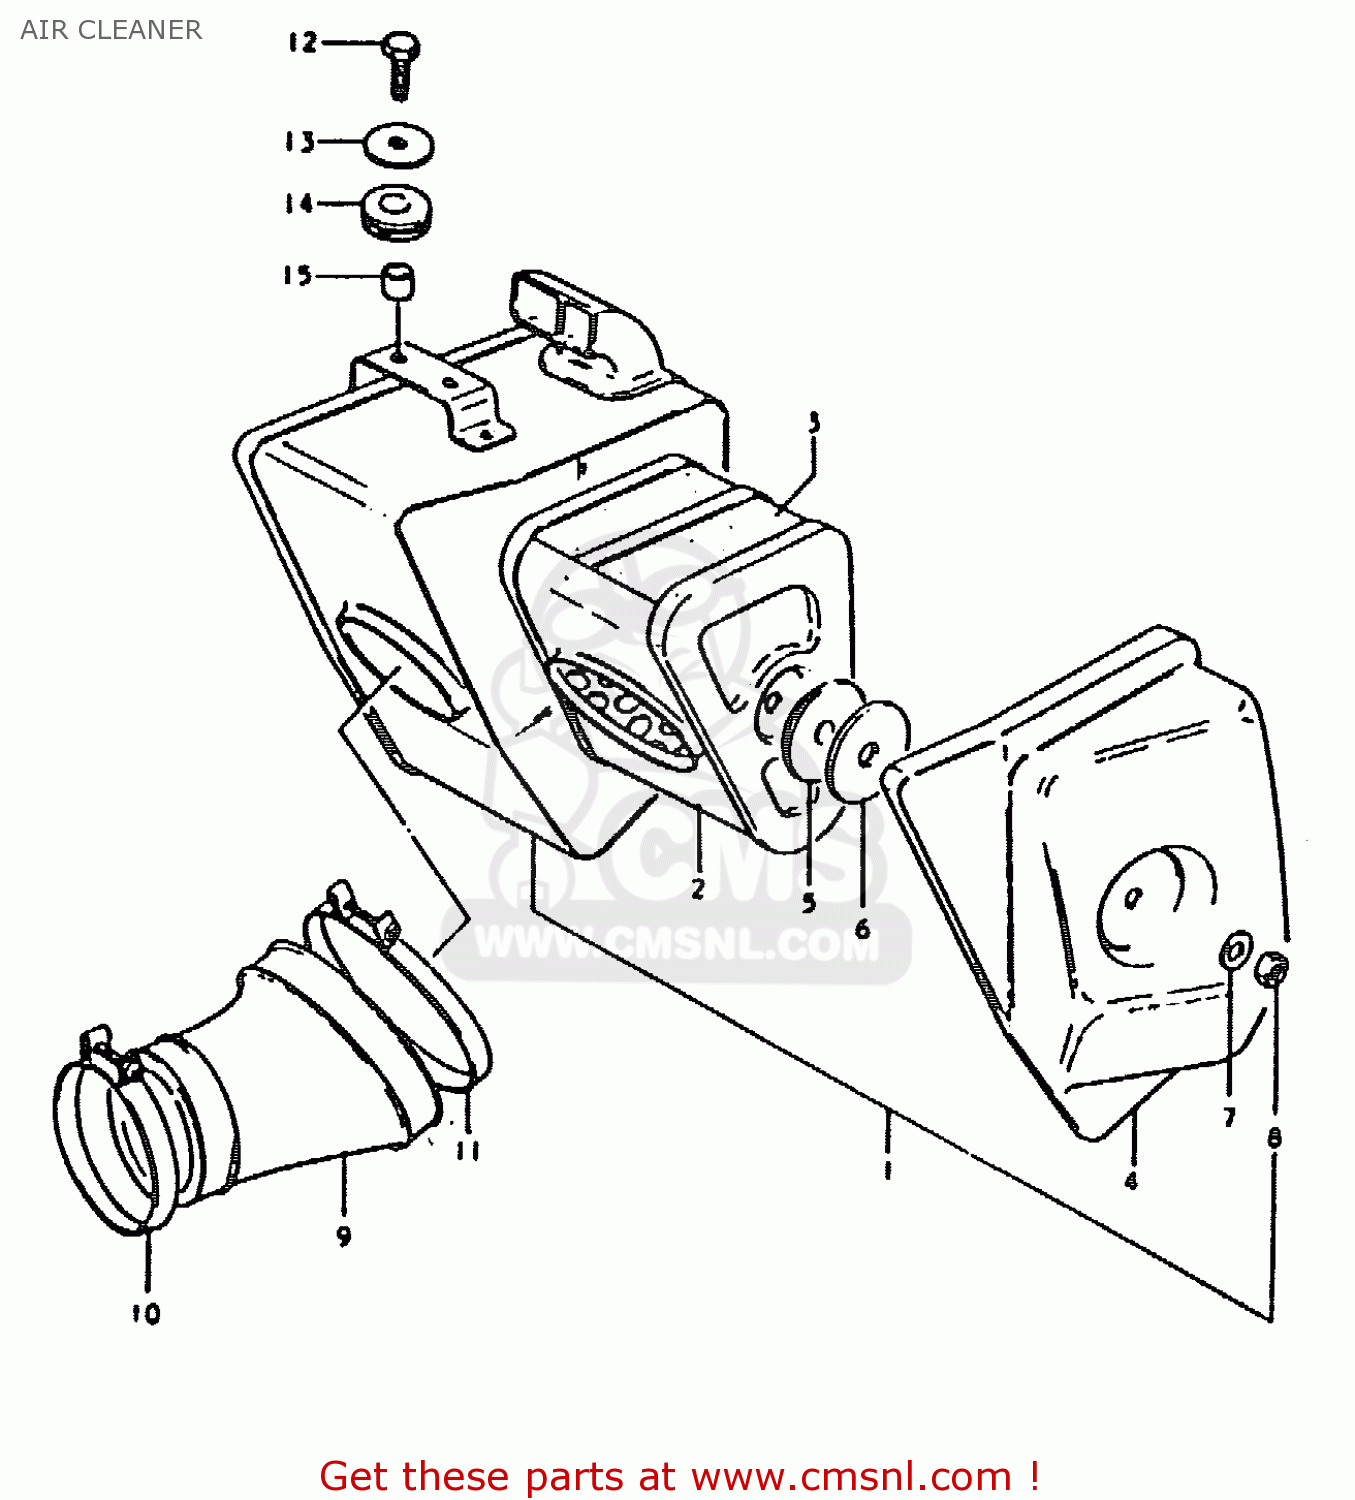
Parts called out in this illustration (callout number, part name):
1	CLEANER ASSEMBLY,AIR
2	FILTER ASSY,AIR CLEANER
3	FILTER
4	CAP
5	SEAL
6	SPACER
7	WASHER
8	NUT
9	TUBE,AIR CLEANER OUTLET
10	CLAMP
11	CLAMP
12	BOLT
13	WASHER (6.5X20X1.2)
14	CUSHION
15	SPACER (7X9X7)
